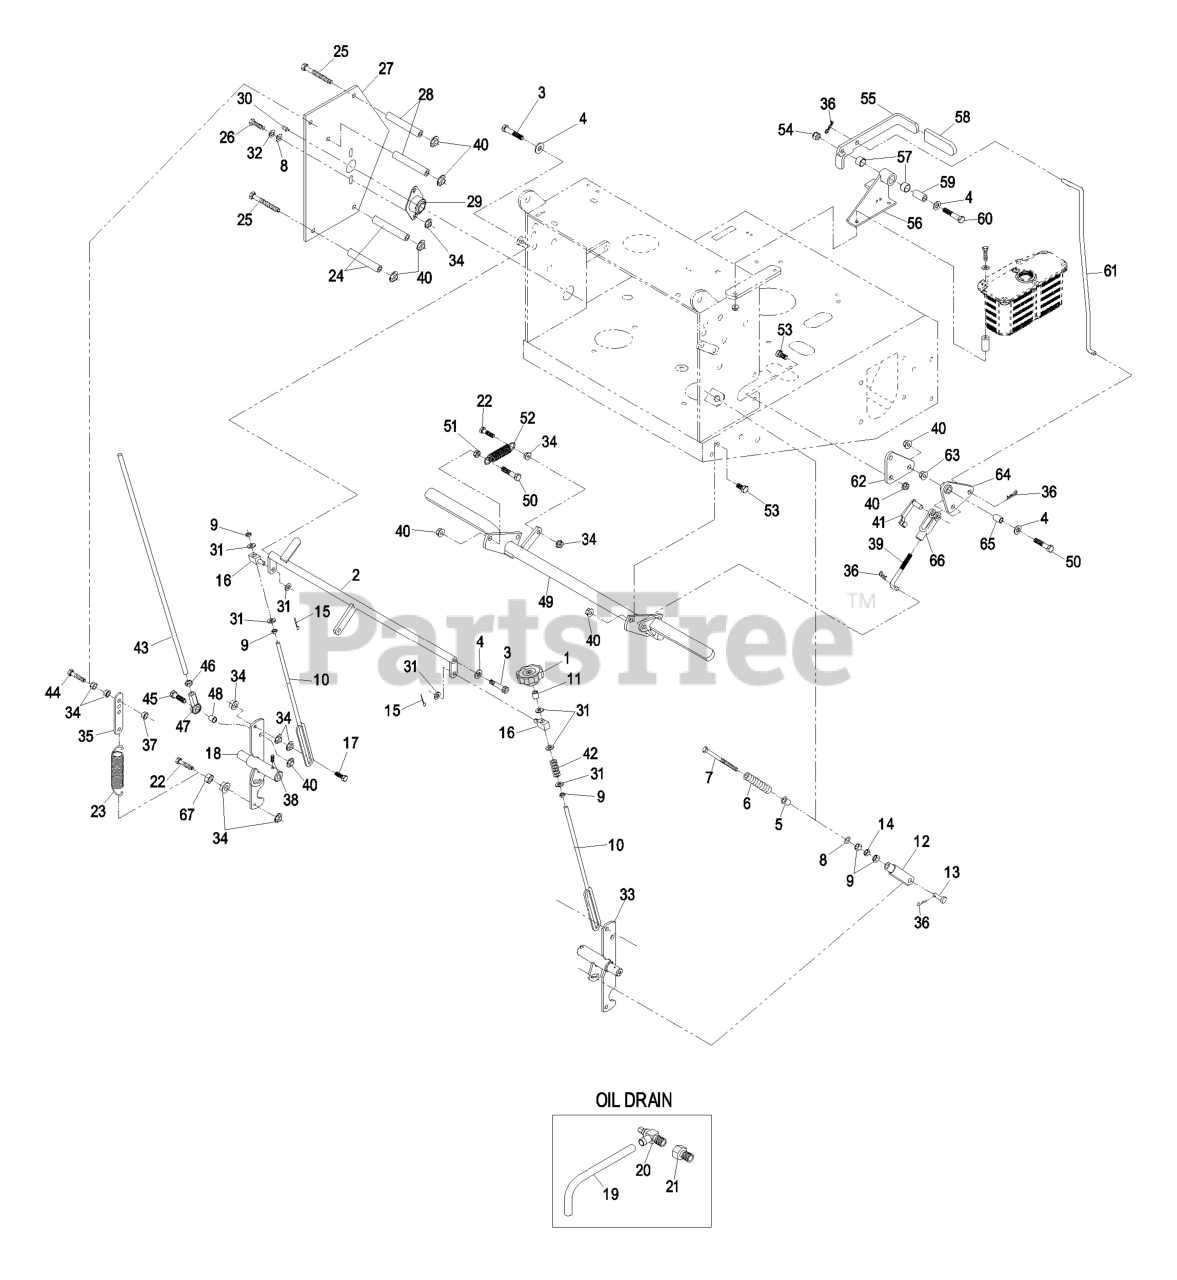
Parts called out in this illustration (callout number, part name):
1	KNOB-TRACKING
2	CRANK-CONTROL, SPEED
3	SCREW-HSH
4	WASHER-FLAT
5	BUSHING-FLANGED
6	SPRING,COMPRESSION (NEUT)
7	BOLT-RETURN, NEUTRAL
8	WASHER-FLAT
9	NUT-HEX
10	LINK-CONTROL, SPEED
12	YOKE-ADJUSTABLE
13	PIN-CLEVIS
14	NUT-JAM
15	PIN-COTTER
17	SCREW-HH
18	SHAFT-CONTROL, LH
19	HOSE-DRAIN, OIL
20	VALVE-DRAIN, OIL
21	ADAPTER
22	SCREW-HH
23	SPRING-EXTENSION
24	SPACER-SHIELD
25	SCREW-HH
26	SCREW-HH
27	SHIELD-CONTROLS, HYDRO
28	SPACER-SHIELD
29	BEARING-FLANGE, SIDE
30	FITTING-GREASE
31	WASHER-PLAIN
32	WASHER-LOCK
33	SHAFT-CONTROL, RH
35	TAB-SPRING, EXTENSION
36	PIN-COTTER
37	NUT-LOCK, NI
38	SCREW-SET
39	LINKAGE-LOWER
40	NUT-HHF, WHIZ
41	PIN-SPRING, CLEVIS
42	SPRING-COMPRESSION
43	LINKAGE,DRIVE (PLT)
44	BOLT-TAP, HH
45	SCREW-HH
46	NUT-HEX JAM, LH
47	JOINT-BALL END, LH
48	SPACER-TUBE, PUMP LINK
49	WLD,PARK BRAKE 32
50	SCREW-HH
51	NUT-JAM
52	SPRING-IDLER
53	SCREW-HH
54	NUT-LOCK, NI
55	LEVER,PARK BRK W/DECAL
56	BRACKET ASM
57	SLEEVE-BUSHING
58	GRIP-LEVER
59	BUSHING-PIVOT
60	SCREW-HH
61	LINKAGE-UPPER
62	BELLCRANK
64	BELLCRANK ASM
65	BUSHING-PLASTIC
66	YOKE-LINKAGE, BRAKE
67	NUT-JAM
